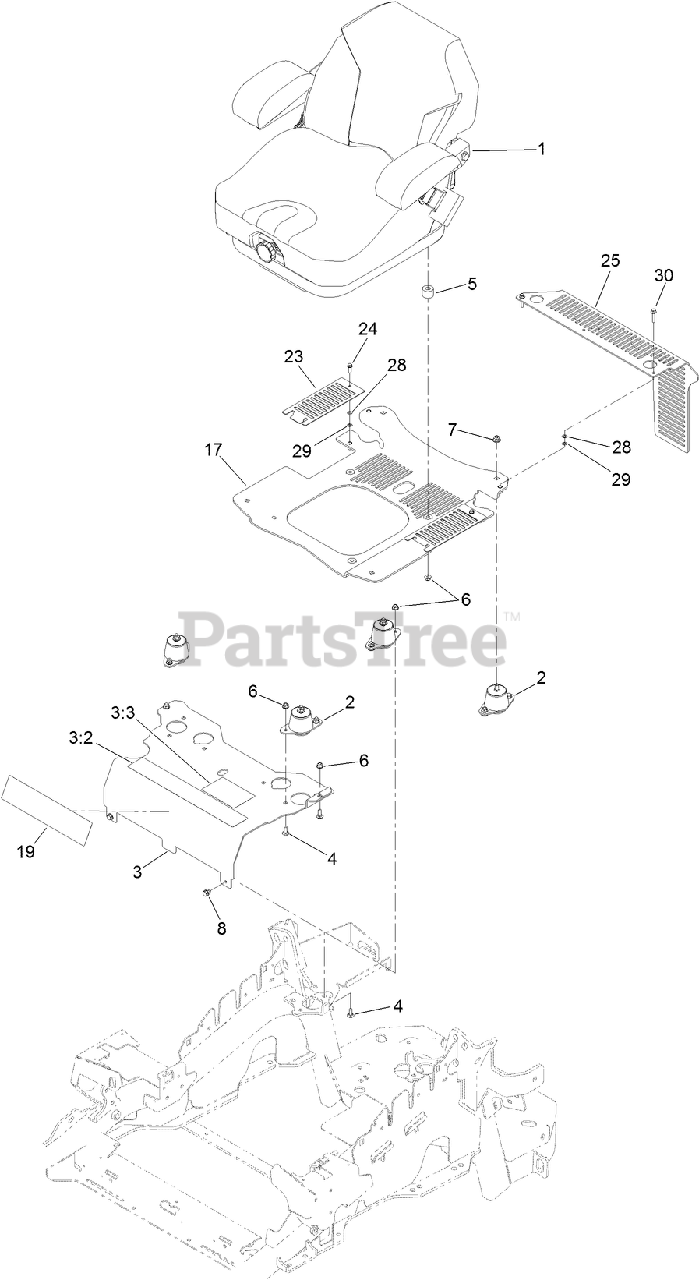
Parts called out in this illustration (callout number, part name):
1	SUSPENSION SEAT ASM
2	ISOLATOR-SEAT
3	MOUNT-SEAT
3:2	DECAL-CONSOLE
3:3	DECAL-SERVICE AID
4	SCREW-CARR
5	SPACER
6	NUT-HF, NI
7	NUT-HF, NI
8	SCREW
17	SEAT BASE ASM
24	SCREW-HWH
25	GUARD-CE
28	WASHER-FLAT
29	NUT-RETAINER
30	SCREW-HHF
